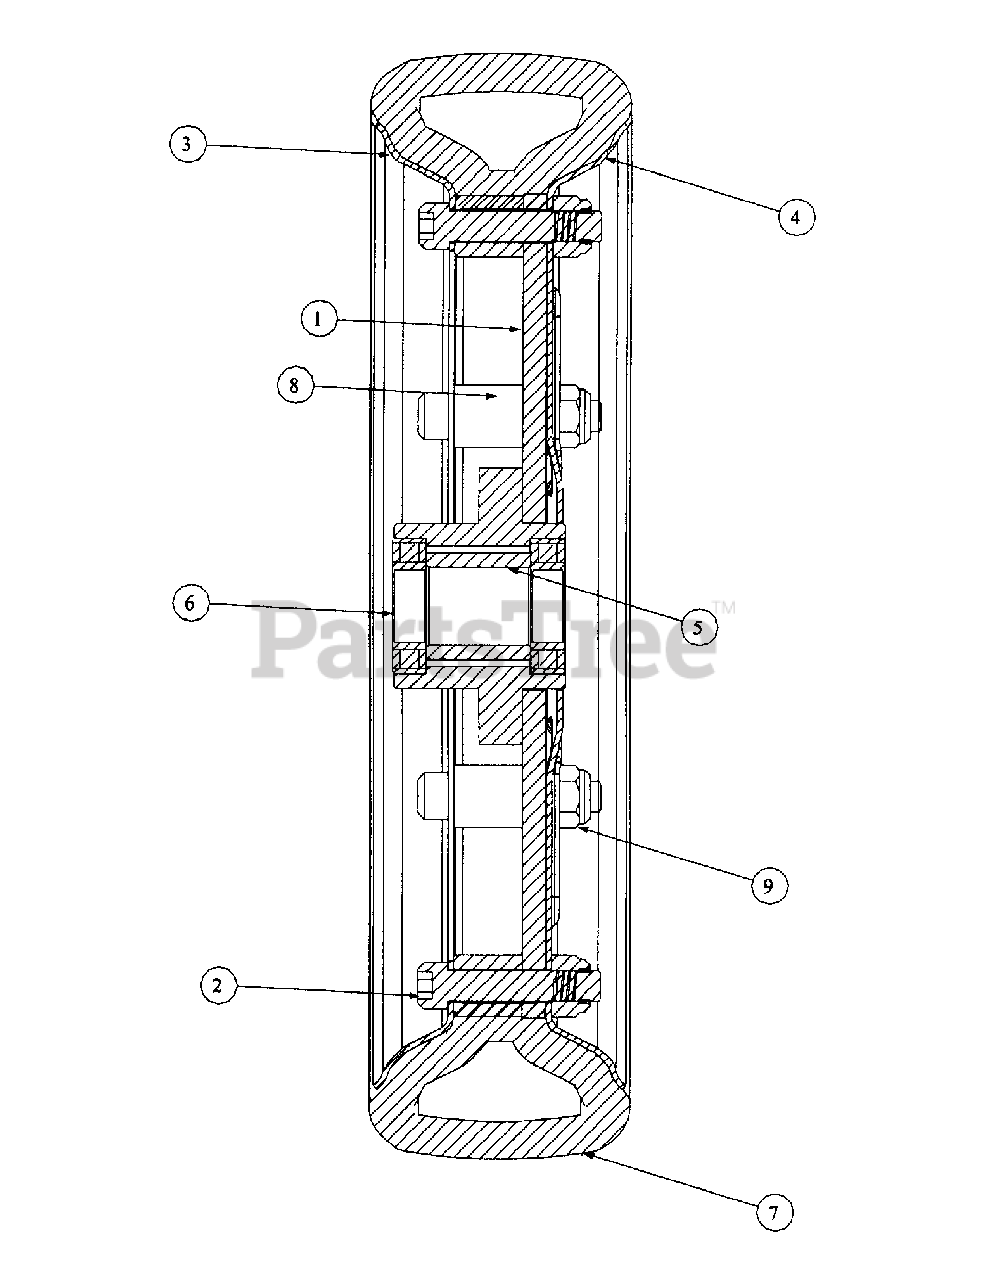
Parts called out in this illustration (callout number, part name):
1	Hub Assembly w/Plate
2	Socket Screw, 1/4-20 x 1.25
3	Wheel Rim, Inner Half
4	Wheel Rim, Outer Half
5	Spacer, .635 I.D x .86 LG.
6	Ball Bearing, 15mm x 28mm x 7mm
7	Tire, 9 x 2.125 ATT
8	Spacer, .265 x .500 x .562
9	Nut, Hex, 1/4-20, Lock
